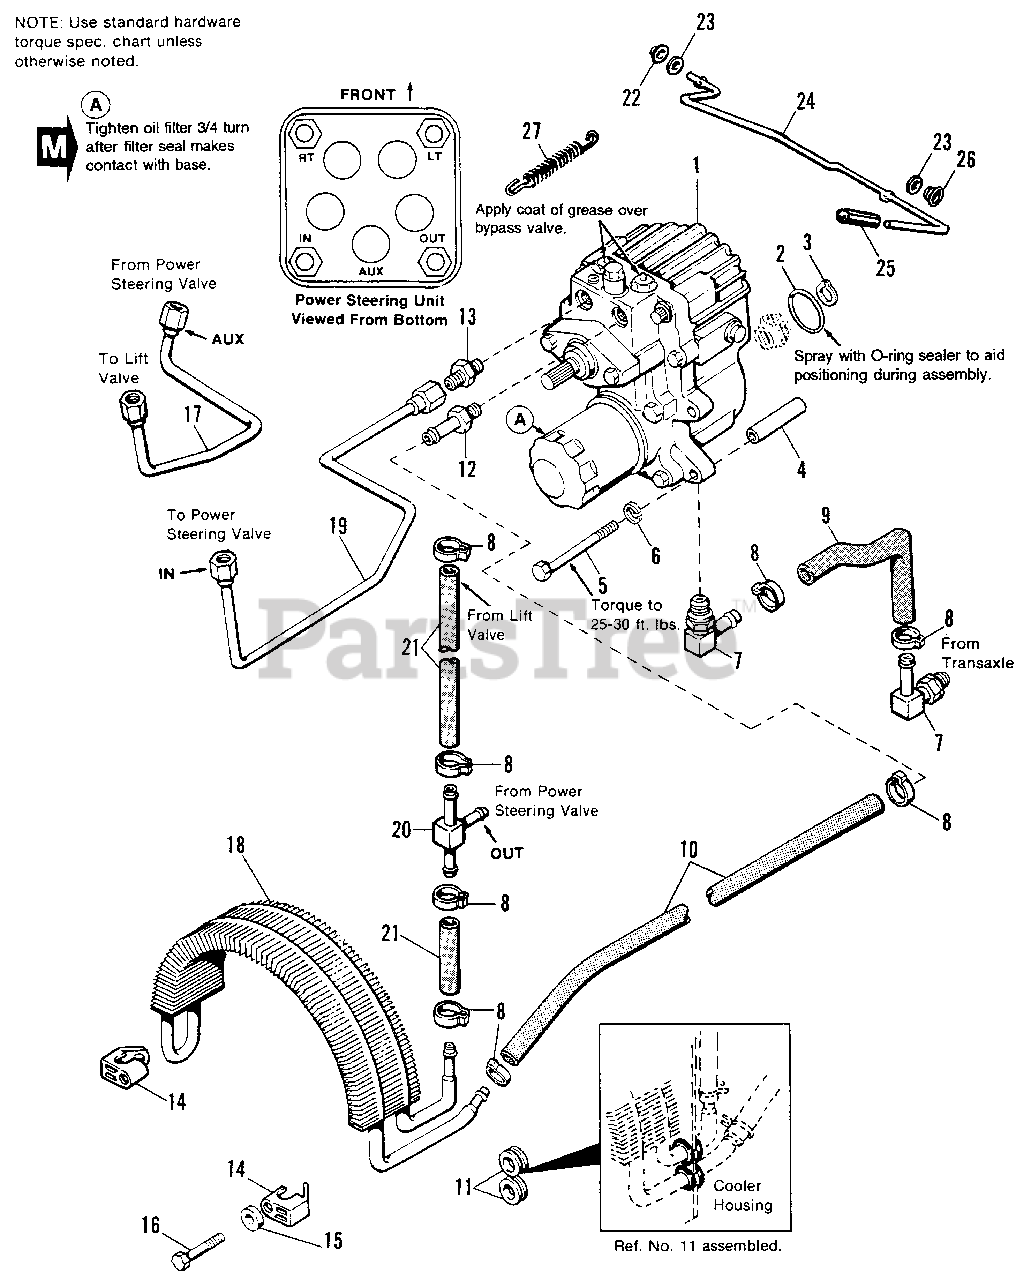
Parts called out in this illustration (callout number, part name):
1	HYDROSTATIC PUMP (See pg. 44 for parts breakdown)
3	RING, Retaining Ext. (.688 Shaft I.D., Early Models)
3	RING, Retaining Ext. (.625 Shaft I.D., Later Models)
4	SPACER, Mounting
5	CAPSCREW, Hex Hd., 3/8-16 x 4, Gr. 5
6	LOCKWASHER, 3/8
7	FITTING, Hyd., 7/8-14 O.R. x 5/8, 90
8	CLAMP, Hose
9	HOSE, Hyd., 5/8" I.D., Preformed
10	HOSE, Hyd., Return (Cooler to Pump)
11	GROMMET, Rubber
12	FITTING, Hyd., 9/16-18 O.R. x 1/2
13	FITTING, Hyd. 9/16-18 O.R. x 9/16-18
14	CLAMP, Oil Cooler
16	SCREW, Plastite, 1/4-20 x 1-1/2
17	TUBE ASSY., Hyd. (P.S. Valve to Lift Valve)
18	COOLER, Oil
19	TUBE ASSY. Hyd. (Pump to Power Steering Valve)
20	FITTING, Hyd., Tee, 1/2 x 1/2 x 3/8
21	HOSE, Hyd., Return
22	PUSH NUT
23	WASHER, 17/64 x 5/8 x 3/64
24	ROD, Hydrostatic Release
25	GRIP, Release Handle
26	SPRING, Tension, Hydro Release
27	SPRING
